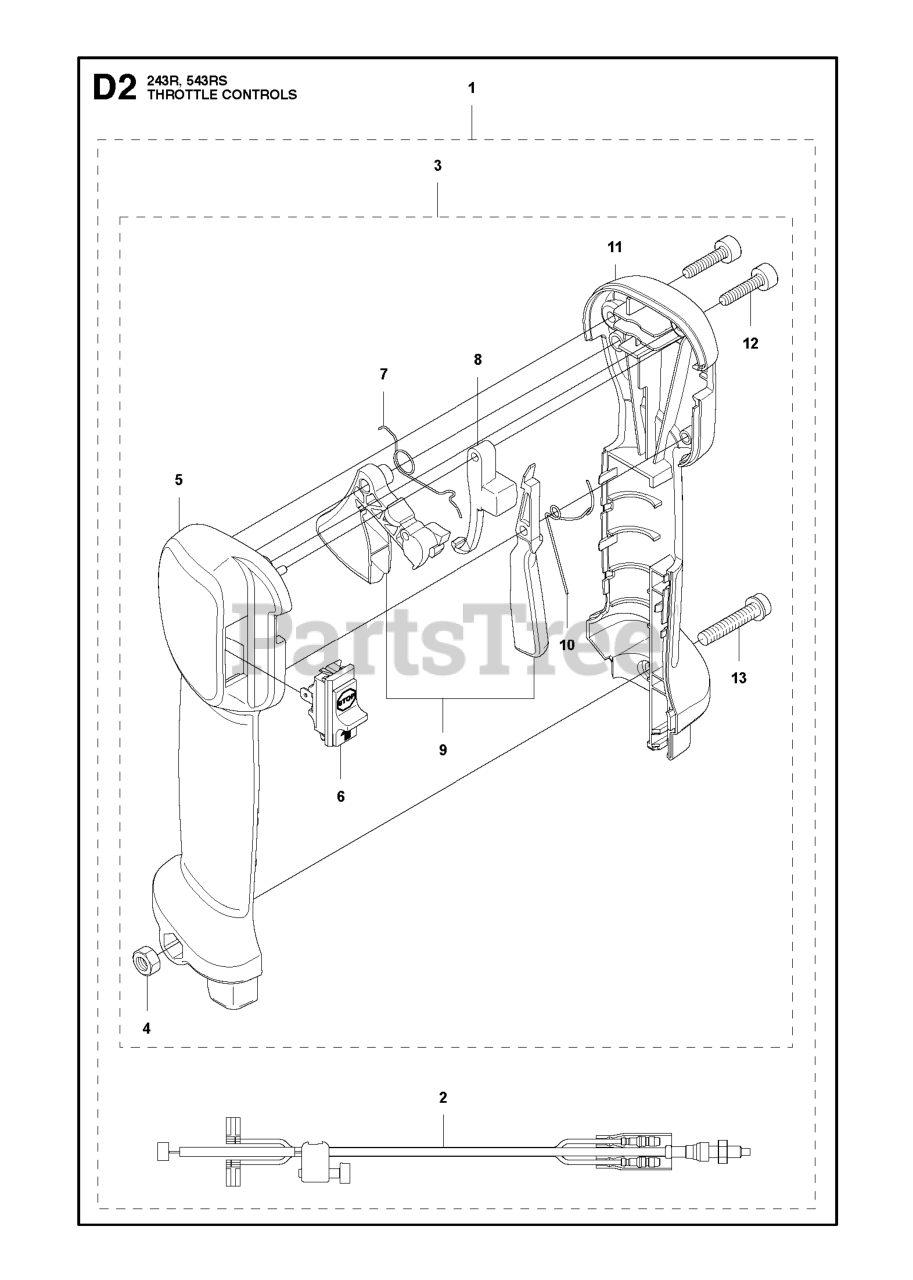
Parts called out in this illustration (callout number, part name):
1	THROTTLE CONTROL ASSY 243R 253
2	THROTTLE CABLE ASSY
3	HANDLE SYSTEM ASSY
6	STOP BUTTON
8	LOCKOUT STARTER THROTTLE
9	THROTTLE CONTROL
13	SCREW
